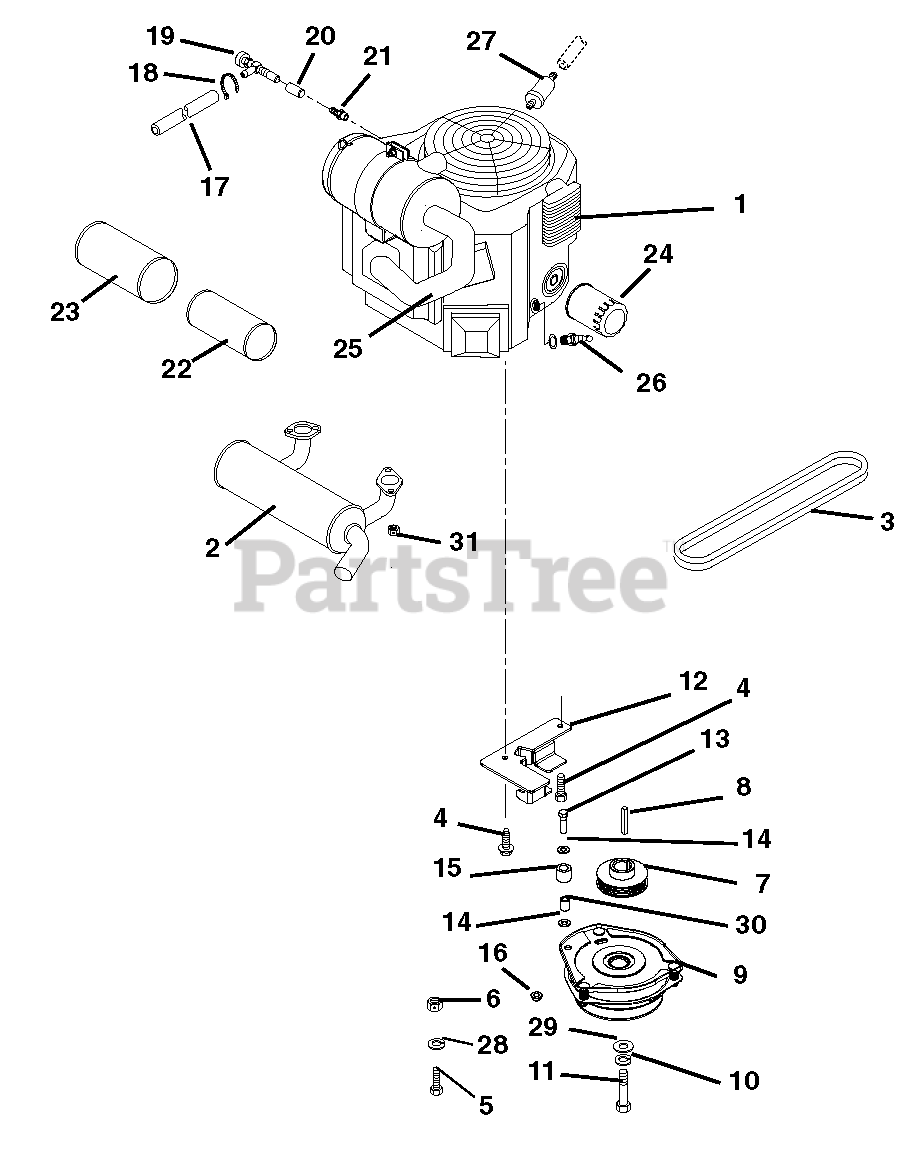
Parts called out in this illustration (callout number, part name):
1	Engine, Kohler (CV740S) (190)
2	Muffler, Kawasaki Vertical (188, 189, 191, 192, 193)
3	Belt, Poly-V
4	Screw, Tapping Hex Washer Head .38-16 x 1.50 (190)
5	Bolt, Hex .31-18 x 1.75 Grade 5 (190)
6	Nut, Locking Top Flange .31-18 (190)
7	Sheave, Poly V 1.127 x 3.275
8	Key, Square .25 x 3.50 x .25 SA
9	Clutch, Electric
10	Washer, Locking .44 x .109
11	Bolt, Hex .44-20 x 3.00 Grade 5 YZ EP80 (190)
12	Anchor, Clutch
13	Bolt-Hex .38-16 x 1.50 Grade 5
14	Washer-Flat-Steel .406 x .812 x .065
15	Bumper, Rubber .62 x 1.0 x .88 LG
16	Nut, Locking-Top-Flange .38-16
17	Gas Line, Bulk .25 I.D.
18	Cable Tie LG 5-1/2
19	Drain, 1/2" Drain
20	Adapter, .38 NPTF (190)
21	Nipple, Pipe .375-18 NPTF x 3.00 (190)
22	Element, Inner Safety (188, 189, 191, 192, 193)
23	Element, Outer Primary (188, 189, 191, 192, 193)
24	Oil Filter (188, 189, 191, 192, 193)
25	Hose, Air Intake (190)
26	Spark Plug (188, 189, 191, 192, 193)
27	Fuel Filter (188, 189, 191, 192, 193)
28	Washer, Locking-EXT.326 x .599 x .031 (190)
29	Washer, Flat Steel .469 x 2 x .25
30	Bushing, .407 x .625 x .813
31	Nut, Locking, Top M8-1.25
